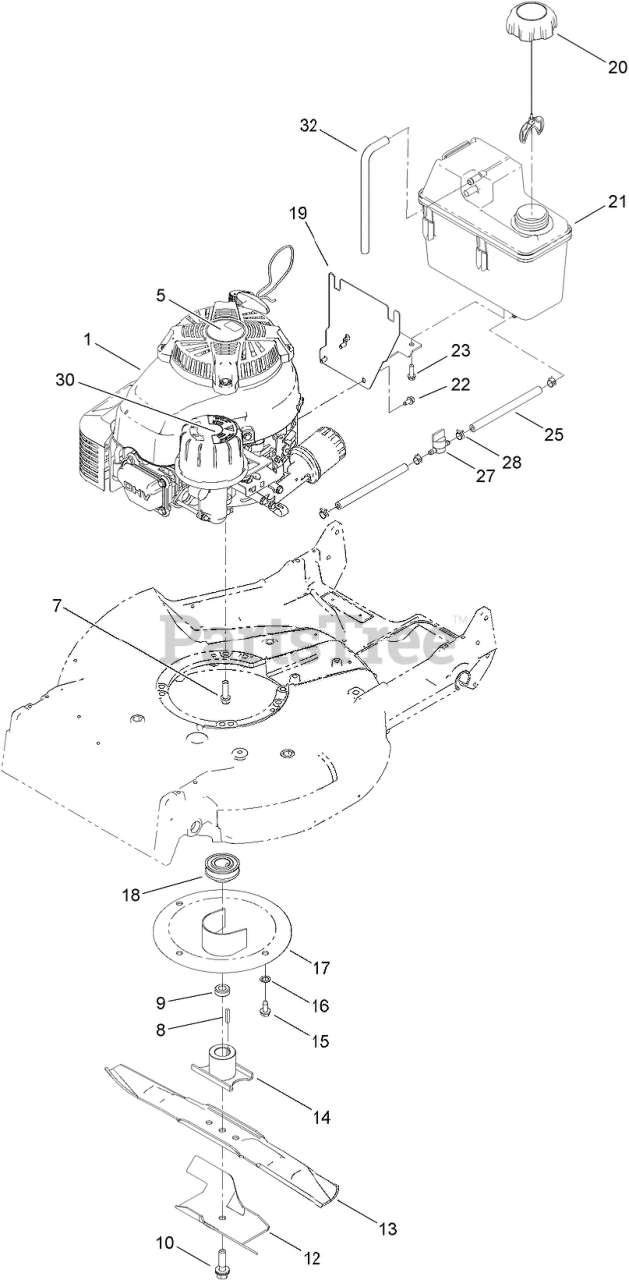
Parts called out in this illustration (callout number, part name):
1	ENGINE-KAWASAKI, FJ180V-BM08-M
7	SCREW-TAPTITE
8	KEY-SQUARE
9	Spacer-Retainer, Blade
10	BOLT-BLADE
12	STIFFENER-BLADE
13	BLADE-21 INCH
14	RETAINER-BLADE
15	SCREW-HWHTF
16	WASHER-LOCK, INTERNAL
17	CRANKSHAFT PROTECTOR ASM
18	PULLEY-DRIVER
19	MOUNT-TANK
20	CAP-RATCHET, TETHERED
21	TANK-FUEL
22	SCREW-HWH
23	SCREW-HWH
25	HOSE-FUEL
27	VALVE-FUEL
28	CLAMP-HOSE
32	HOSE-VENT, CANISTER
